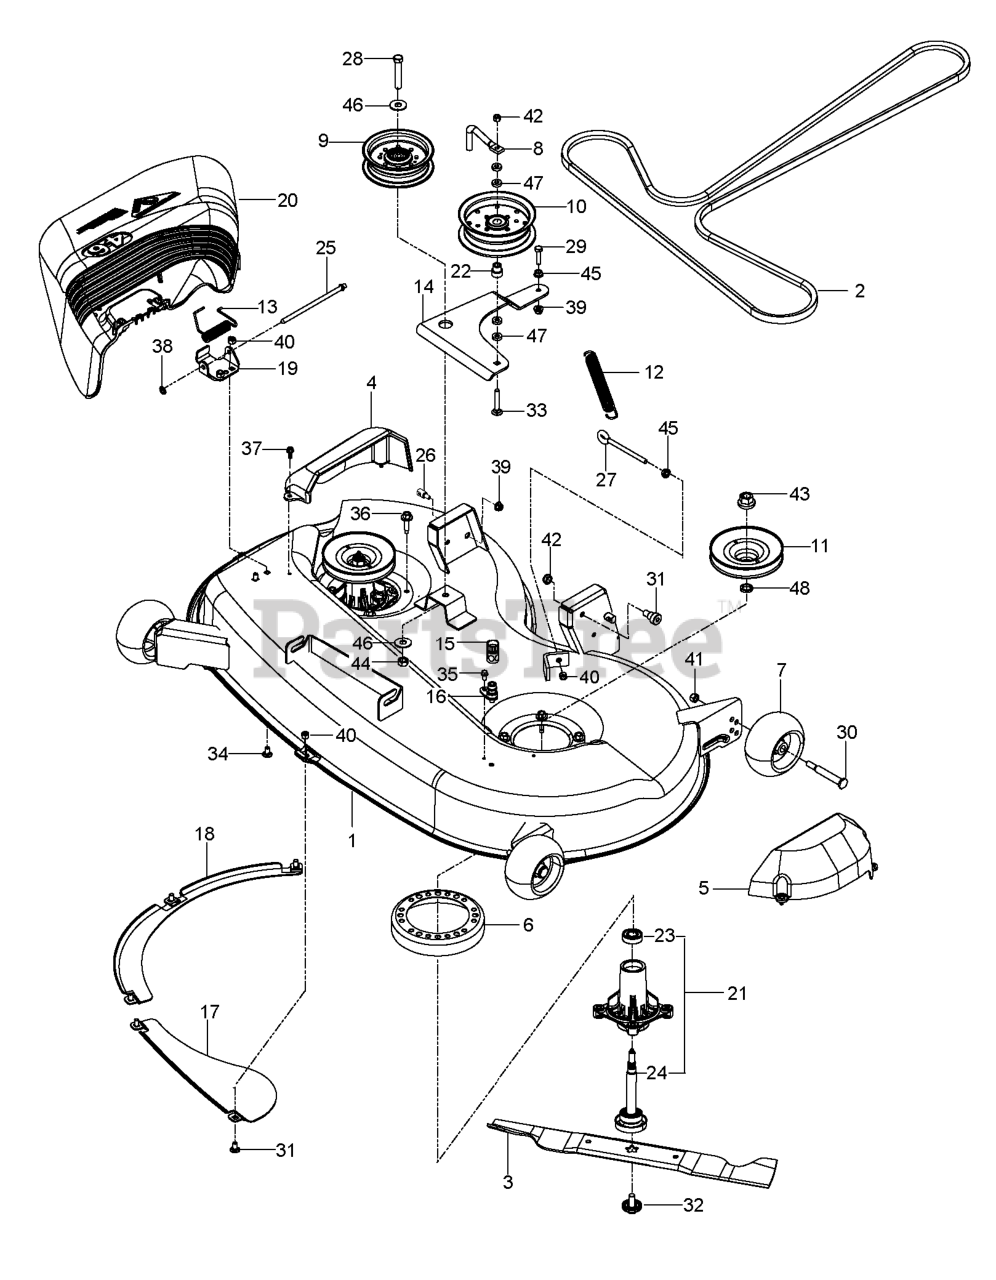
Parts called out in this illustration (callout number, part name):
1	DECK SVC 46"W/DECALS ORG
3	BLADE.MOWER.46".HI.LIFT
4	COVER.MANDREL.RH.46"
5	COVER.MANDREL.LH.46"
6	STRIPPER.MANDREL.ROUND.BLACK
7	RP WHEEL. GUAGE RALLY
8	BELT KEEPER 5"
9	PULLEY.IDLER.MWR.STATI.LH
10	PULLEY, IDLER
11	RP.PULLEY, DECK
12	SPRING, DECK BELT
13	SPRING, TORSION
14	ARM, IDLER BLK
15	COUPLING.QUICK CONNECT
16	PORT.WASHOUT
17	BAFFLE CENTER FRONT
18	BAFFLE FRONT RH
19	BRKT.DEFLECTOR.38"2005+
20	SHIELD.DEFLECTOR.MOWER.46"BLAC
21	MANDREL ASM
22	IDLER BUSHING
24	SHAFT ASM W/LOWER BEARING
25	ROD.HINGE
26	STUD.FASTNER.W/ANTI-ROTATE
27	EYE BOLT 5/16 X 3.50
28	BOLT 7/16-14 X 2-1/2 GR 5 ZD
29	BOLT.5/16-18X1-1/4 FULL.THREAD
30	BOLT.SHOULDER.3/8-16X3-5/8.
31	SB 3/8-16 X 3/8 SKT HD ZD
32	BOLT.WASHER.ASM.7/16-2
33	CARRIAGE BOLT 3/8-16 X
34	BOLT 5/16C X 3/4" CARRIAGE
35	SCREW #10 X 1/2 SELF TAPPING
36	BOLT.HEX.WASHR.HED.313-18X1.19
37	SCREW.1/4-20X5/8
38	NUT PUSH M
39	5/16-18 NYLOC FLANGE NUT
40	NUT.71038.31-18.HEX.NYLOCK
41	NUT LOCK FLG 3/8-16 UNC
42	NUT HEX 3/8-16 NYLON, THIN
43	NUT.FLANGE.LOCK.TOP
44	7/16-14 HEX NUT W/NYL RING ZD
45	NUT 5/16C WHIZ
46	WASHER
47	WASHER 3/8 X 3/4 X .187 TK
48	WASHER.SPACER.MANDREL
